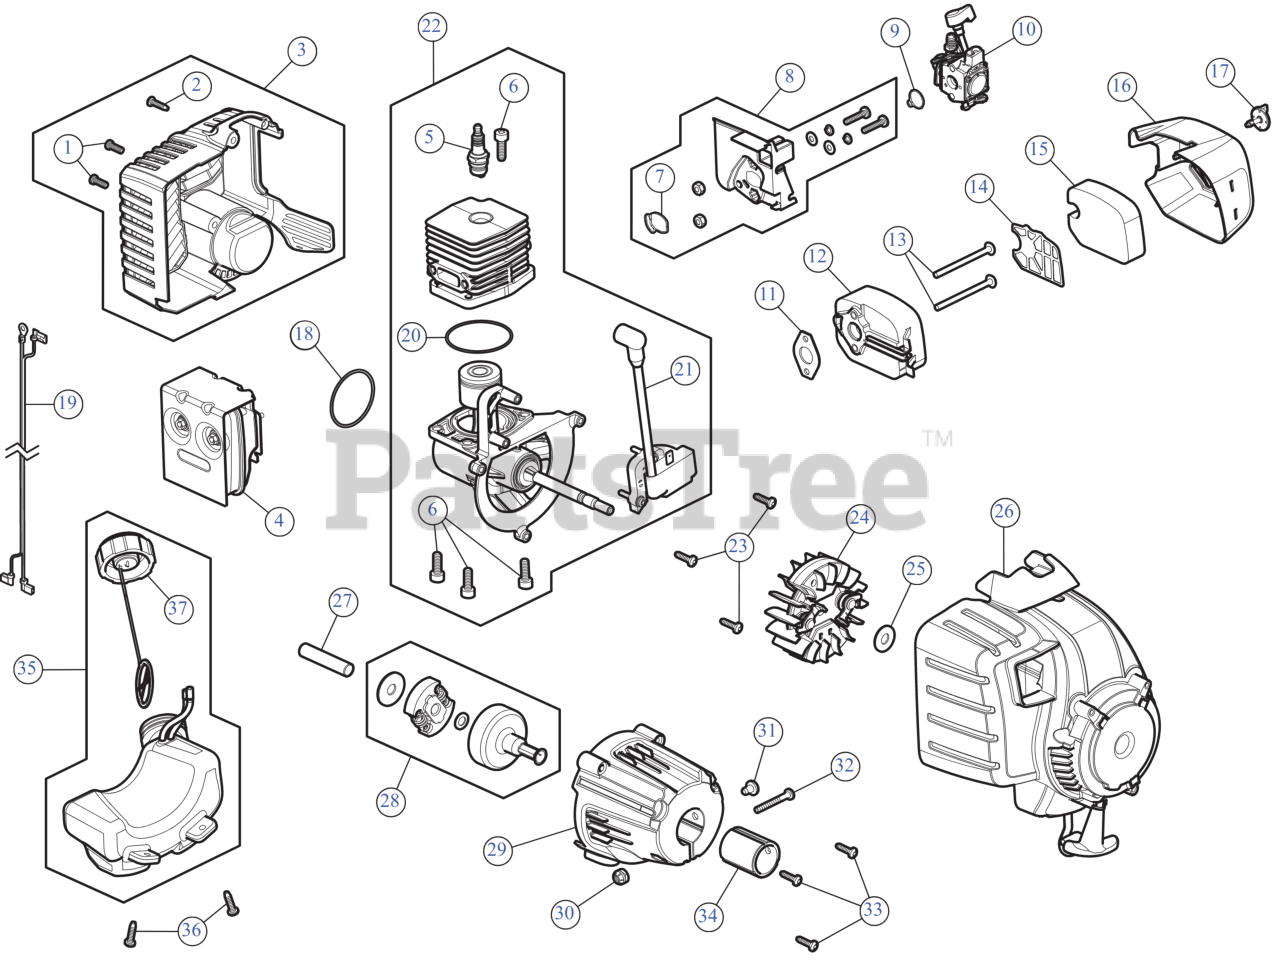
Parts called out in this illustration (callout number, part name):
1	SCREW:10-32X.562:#8P
2	SCREW, #8-16X.750 PH
3	HOUSING-ENGINE REAR
4	MUFFLER ASSEMBLY
5	SPARK PLUG
6	SCREW, 1/4-20 x .75
7	O-RING
8	INTAKE ASSEMBLY
9	O-RING
10	CARBURETOR
11	GASKET CARB
12	AIR CLEANER BASE
13	SCREW 10-32X2.5
15	FILTER
16	AIR CLEANER COVER
17	KNOB COVER
18	O-RING
19	LEAD WIRE
20	O-RING
21	MODULE
22	SHORTBLOCK
23	SCREW:10-32X.562:#8P
24	FLYWHEEL ASSEMBLY
25	BELL WASHER
26	STARTER HOUSING
27	SPACER
28	SMALL CLUTCH ASSEMBLY W/SMALL DRUM
29	CLUTCH COVER ASSEMBLY
30	HEX NUT
31	SCREW 1/4-20X3/8
32	SCREW
33	SCREW, #8-16X.750 PH
34	RUBBER SPACER
35	FUEL TANK
36	SCREW:10-6 x .75
37	FUEL CAP ASSEMBLY
